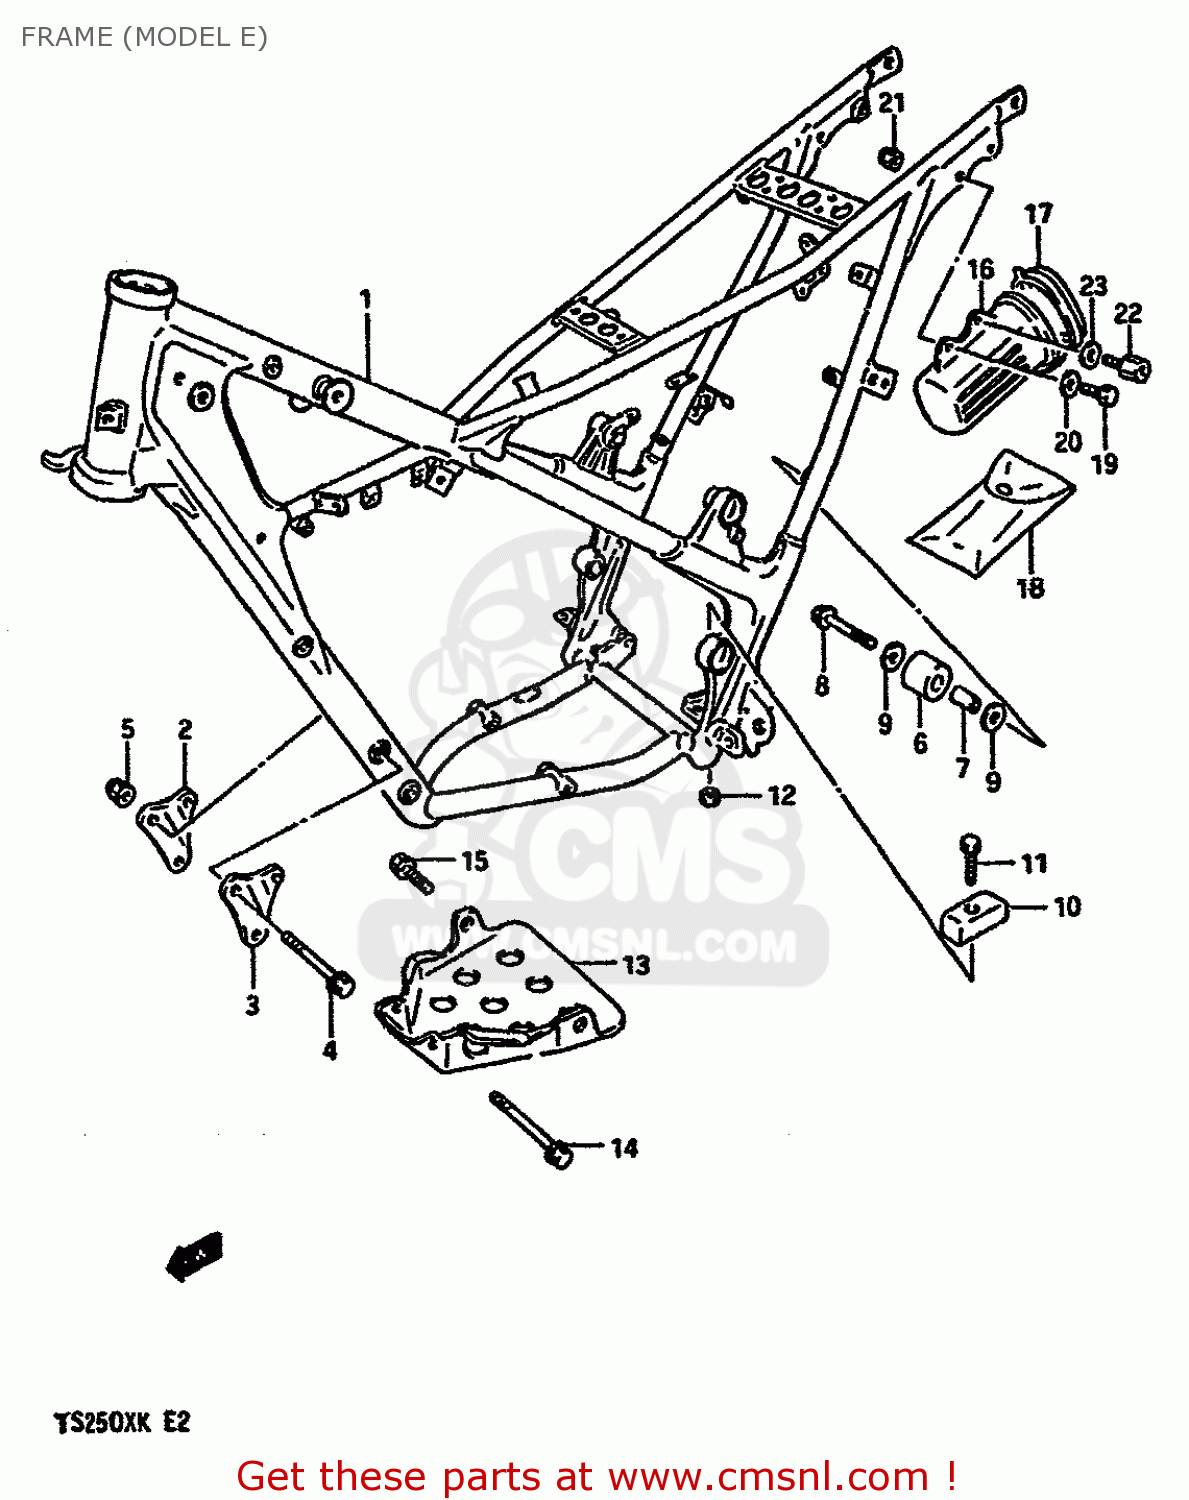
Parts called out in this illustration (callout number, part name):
1	FRAME (BLUE)
2	PLATE,ENGINE MOUNT RH
3	PLATE,ENGINE MOUNT LH
4	BOLT
5	NUT
6	ROLLER,CHAIN LENGTH CONTROL
7	SPACER,CHAIN LENGTH ROLLER
8	BOLT(8X45)
9	WASHER
10	GUIDE,CHAIN CONTROL
11	BOLT
12	NUT
13	PROTECTOR,ENGINE
14	BOLT 8X90
15	BOLT(8X205)
16	HOLDER,TOOL
17	CAP,TOOL HOLDER
18	TOOL ASSY
19	BOLT
20	WASHER (6.5X18X1.6)
21	NUT
22	BOLT,TOOL HOLDER REAR
23	WASHER (6.5X18X1.6)
